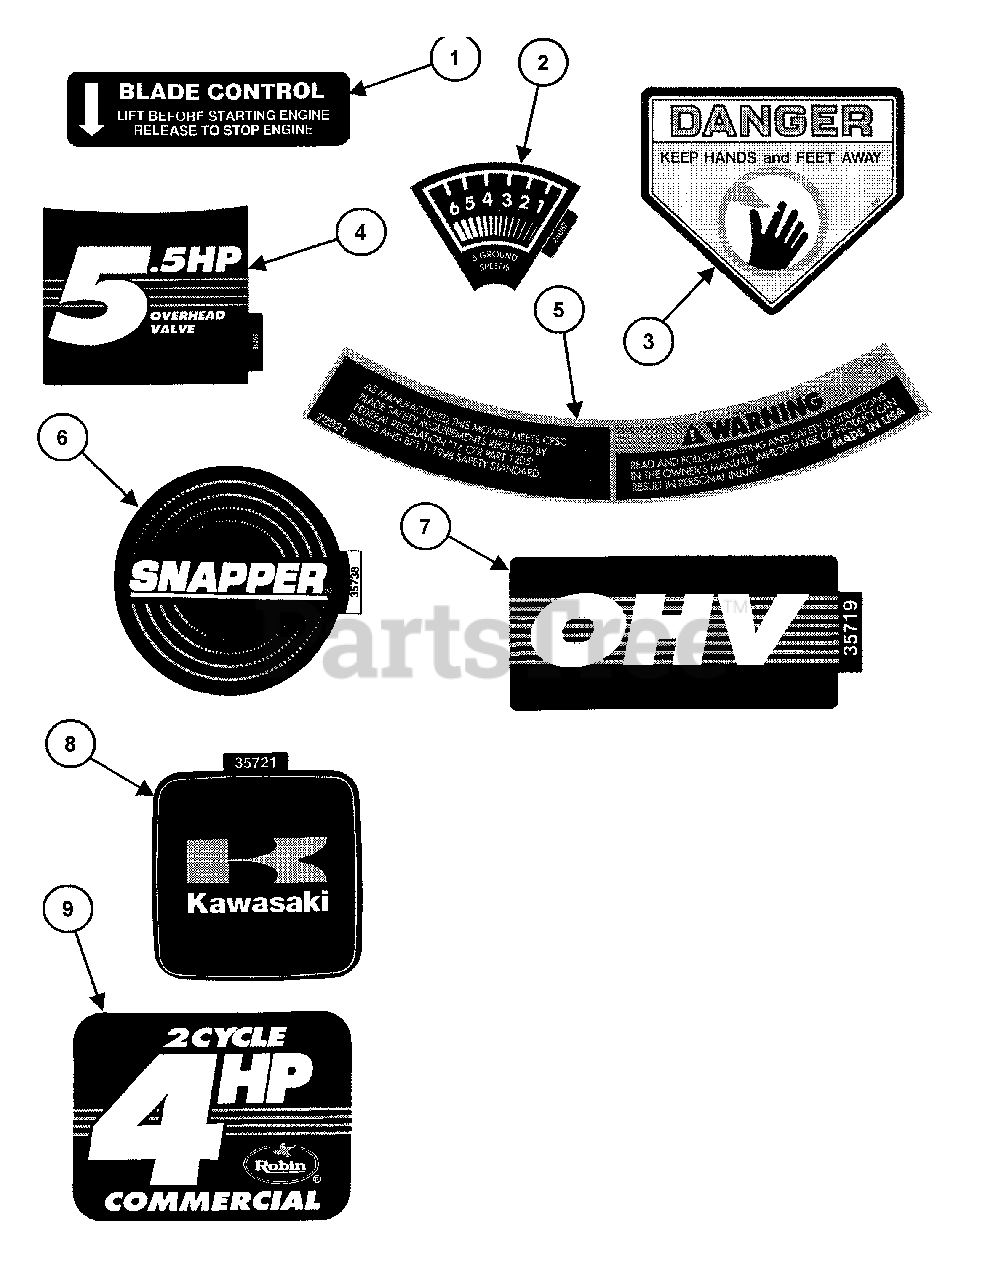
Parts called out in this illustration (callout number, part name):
1	DECAL, Blade Control
2	DECAL, Speed Sector
3	DECAL, Danger
4	DECAL, 5 HP Overhead Valve (Black & Gold)
5	DECAL, Warning Deck
6	DECAL, Snapper (3.38 Dia.) (Black & Gold)
7	DECAL, OHV (Overhead Valve) (Black & Gold)
8	DECAL, Kawasaki (Black & Gold)
9	DECAL, 4 HP - 2 Cycle (Black & Gold)
